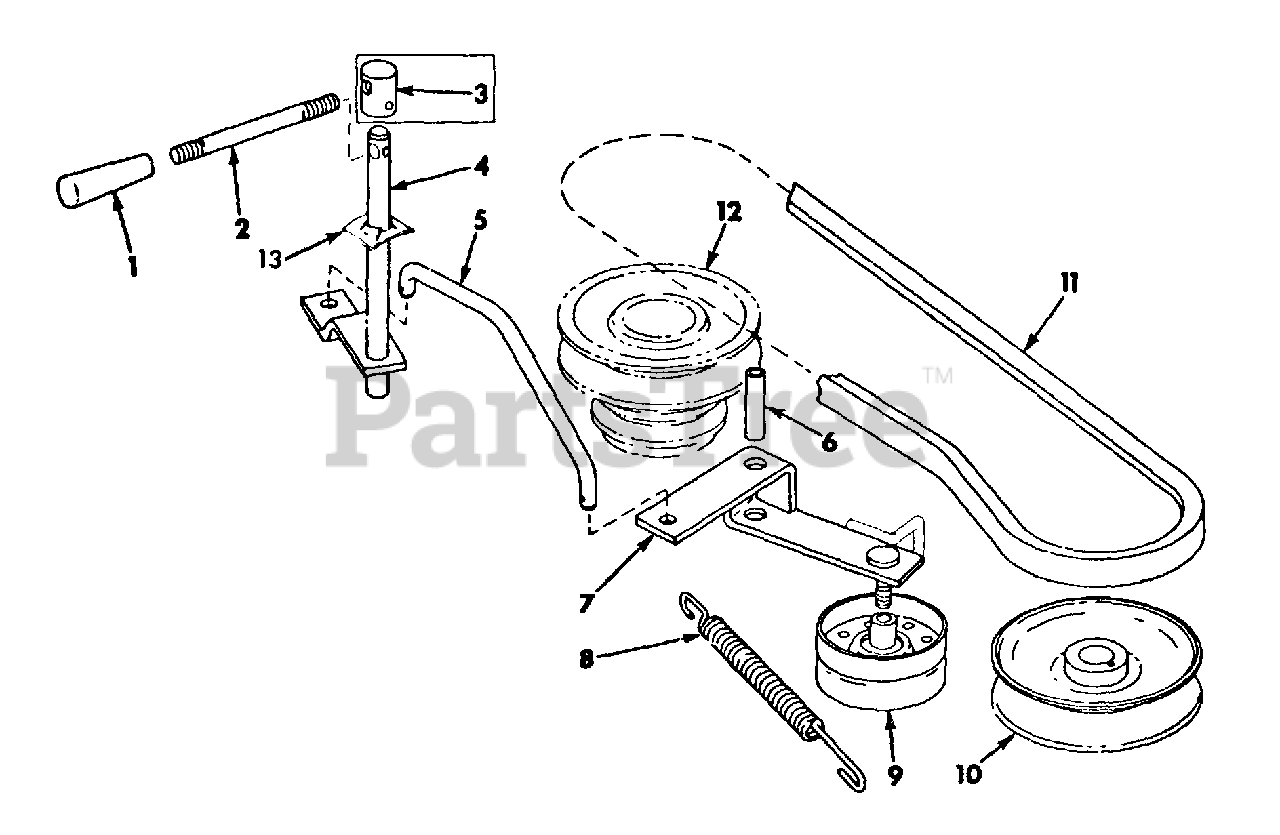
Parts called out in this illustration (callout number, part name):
1	GRIP, SHIFTER HANDLE
2	STUD, SHIFTER HANDLE
3	PIN, MOWER SHIFTER HANDLE
4	LEVER ASSY, MOWER SHIFTER
5	ROD, MOWER SHIFTER
6	BUSHING, SHIFTER ARM
7	LEVER ASSY, IDLER MOWER
8	SPRING, MOWER CLUTCH RETURN
9	PULLEY, MOWER SHIFTER IDLER
10	PULLEY ASSY, MOWER DRIVE
11	BELT, MOWER DRIVE
12	PULLEY, CENTER SPINDLE
13	NUT, SPEED PUSHION TYPE
